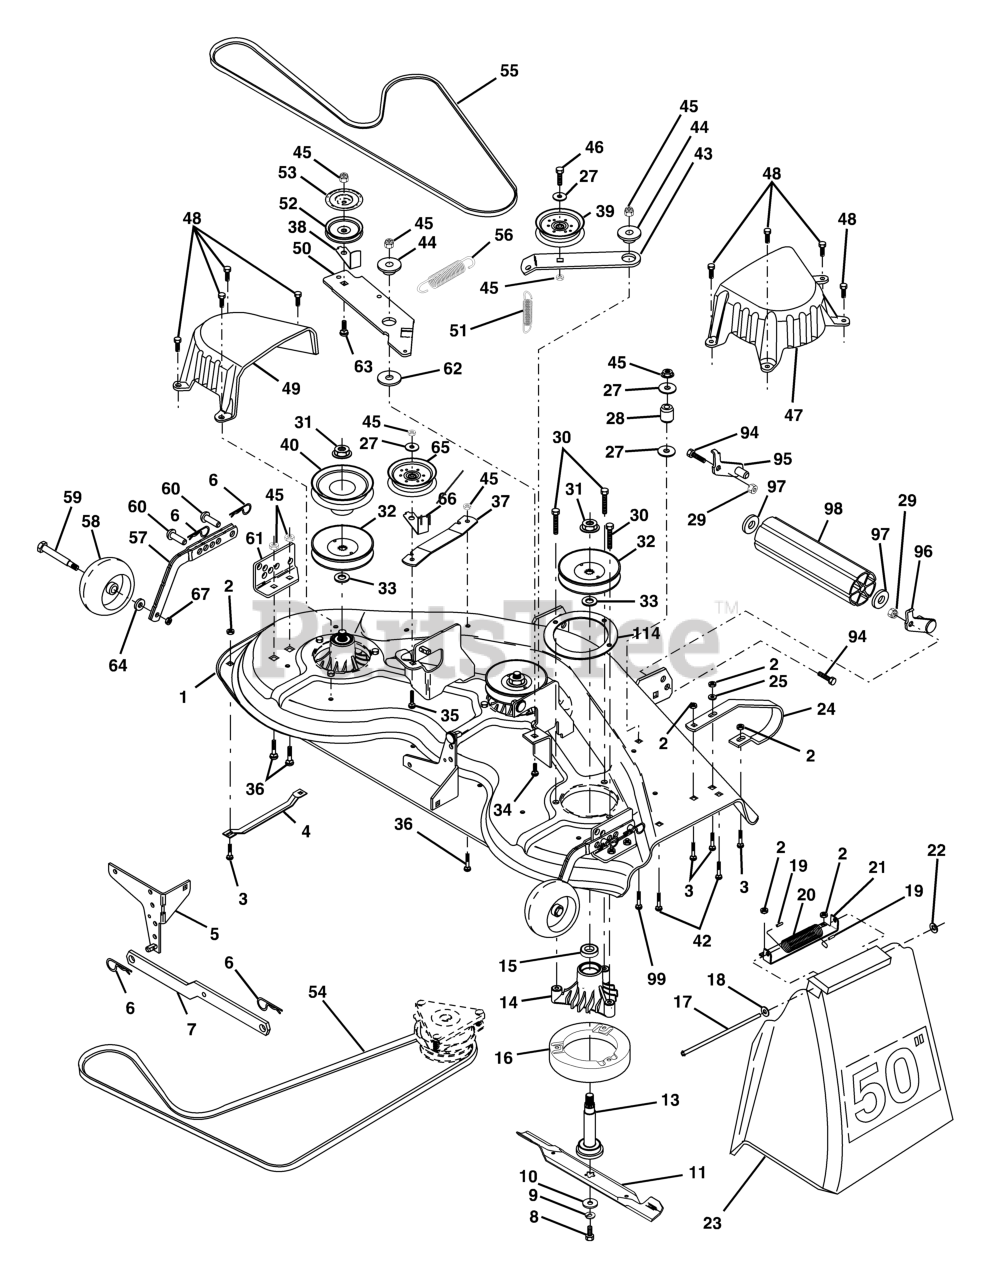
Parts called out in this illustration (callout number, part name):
1	50" DECK ASM
2	LOCKNUT
3	BOLT.CARR.SQNK.5/16-18UNC.X3/4
4	RUNNER-LH M
5	BRACKET SWAY BAR
6	RETAINER-SPRNG RB
7	BAR SWAY DECK
8	BLADE BOLT
9	LOCKWASHER
10	WASHER.BLADE
11	BLADE.50".HI-LIFT
13	SHAFT.ASM.W/BEARING
14	HOUSING.MANDREL.44/46" VENT
16	STRIPPER.MANDREL.ROUND.BLACK
17	ROD-HINGE T
18	Washer 11/32 x 5/8 x 16 Ga.
19	CAP-SLEEVE LT
20	SPRING TORSION
21	BRACKET, DEFLECTOR
22	NUT PUSH M
23	SHIELD.DEFLECTOR.MOWER.50"BLK.
25	WASHER M
26	BOLT
27	WASHER
28	IDLER SPRING SPACER
29	NUT.71038.31-18.HEX.NYLOCK
30	SCREW, WASHER HEAD
31	NUT, FLG TOPLOCK 9/16"
32	PULLEY MANDREL
33	WASHER
34	BOLT.3/8-14X1.25
35	BOLT
36	BOLT D
37	STIFFENER ARM
38	KEEPER.BELT.IDLER.PLATED
39	PULLEY.IDLER.FLAT
40	PULLEY.DRIVEN.DECK.48'
42	RP BOLT 5/16-18 X3/4 ZN/YEL GR
43	ARM.IDLER.SEC.44"
44	SPACER RETAINER
46	BOLT
47	COVER MANDRELL
48	SCREW.1/4-20X5/8
49	COVER.MANDREL.LH.44"
50	ARM.IDLER.PRIMARY
51	SPRING.SEC.44"VEN
52	IDLER PULLEY
53	SHIELD.IDLER.MOWER.50"
54	V-BELT PRIMARY 50"
55	BELT V SECONDARY
57	BAR.ASM.GUAGE.WHEEL
58	WHEEL GAGE DONUT
59	BOLT, SHOULDER
60	PIN.CLEVIS
61	BRACKET.GUAGE.WHEEL
62	HARDENED WASHER
63	BOLT.3/8-16X1.50
64	WASHER.5/16.FLAT.STE.STD.
65	PULLEY IDLER FLAT MWR
66	KEEPER BELT IDLER PLATED
67	LOCKNUT
94	BOLT RB
95	BRACKET ASM, ROLLER (L)
96	BRACKET ASM, ROLLER
97	Washer 17/32 x 7/8 x 16 Ga.
98	NOSE ROLLER
114	REINFORCEMENT MANDREL RING
114	KIT.MANDREL.ASM.44"/46/50"SRVC
